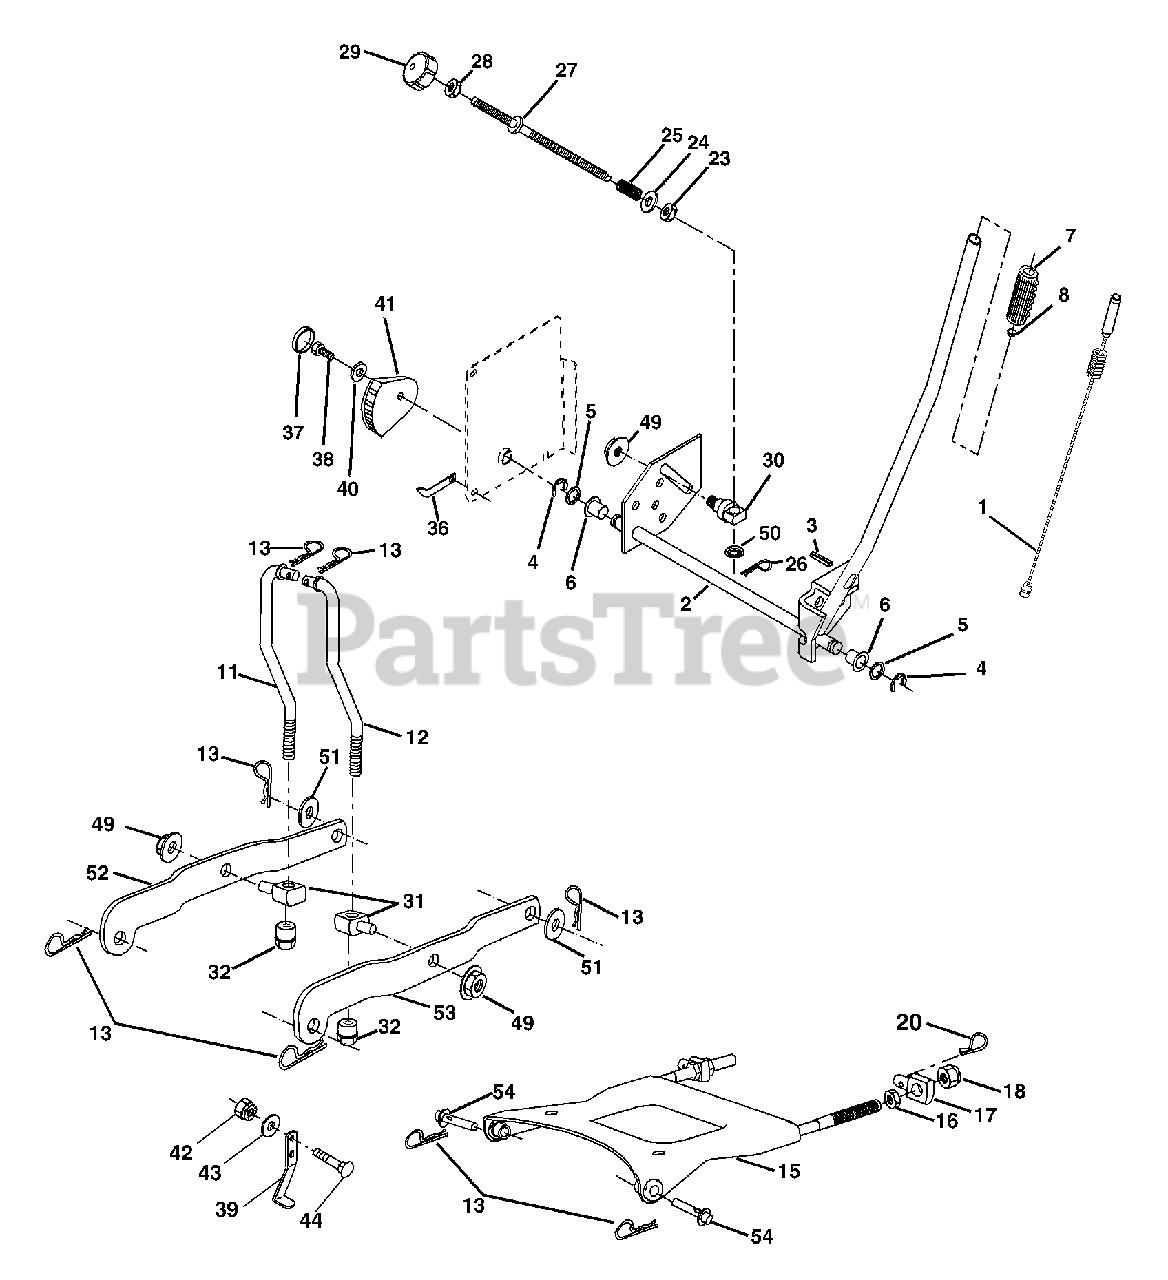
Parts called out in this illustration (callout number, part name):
1	Wire Asm Inner/Sprg W/plunger
2	Shaft Asm Lift RH w/Inf
3	Pin Groove
4	E Ring #5133-62
5	Washer 21/32 X 1 X 21 Ga
6	Bearing Nylon Blk 629 Id
7	Grip Handle
8	Button Plunger
11	Link Lift LH
12	Link Lift RH
13	Retainer Spring
15	Plate Asm. Suspension Front
16	Nut Jam Hex 1/2-13 Unc
17	Trunnion Front Susp.
18	Nut Lock w/Wsh 1/2-13unc
20	Retainer Spring
23	Nut Special
24	Washer 13/32 X 5/8 X 16 Ga
25	Spring
26	Retainer Clip
27	Rod Adj Lift
28	Nut Hex Jam 3/8-16 Unc
29	Knob Inf 3/8-16 Unc Blk W/sym
30	Trunnion Infin Height
31	Trunnion Infin Height
32	Nut Lift Link Zinc Clear
36	Pointer Height Indicator
37	Plug Hole Blk 1.485/1.515 Dia.
38	Screw 5/16-18 x 1
39	Upstop
40	Washer 11/32 x 1-1/2 10 Ga.
41	Indicator Height STLT
42	Nut Crownlock 3/8-16 Unc
43	Washer 13/32 x 1 x 12 Ga.
44	Bolt Carr 3/8-16 Unc
49	Nut Hex Flange Lock
50	Nut Push Phos & Oil
51	Washer 17/32 x 7/8 x 16 Ga.
52	Arm Susp. Rear LH
53	Arm Susp. Rear RH
54	Pin
